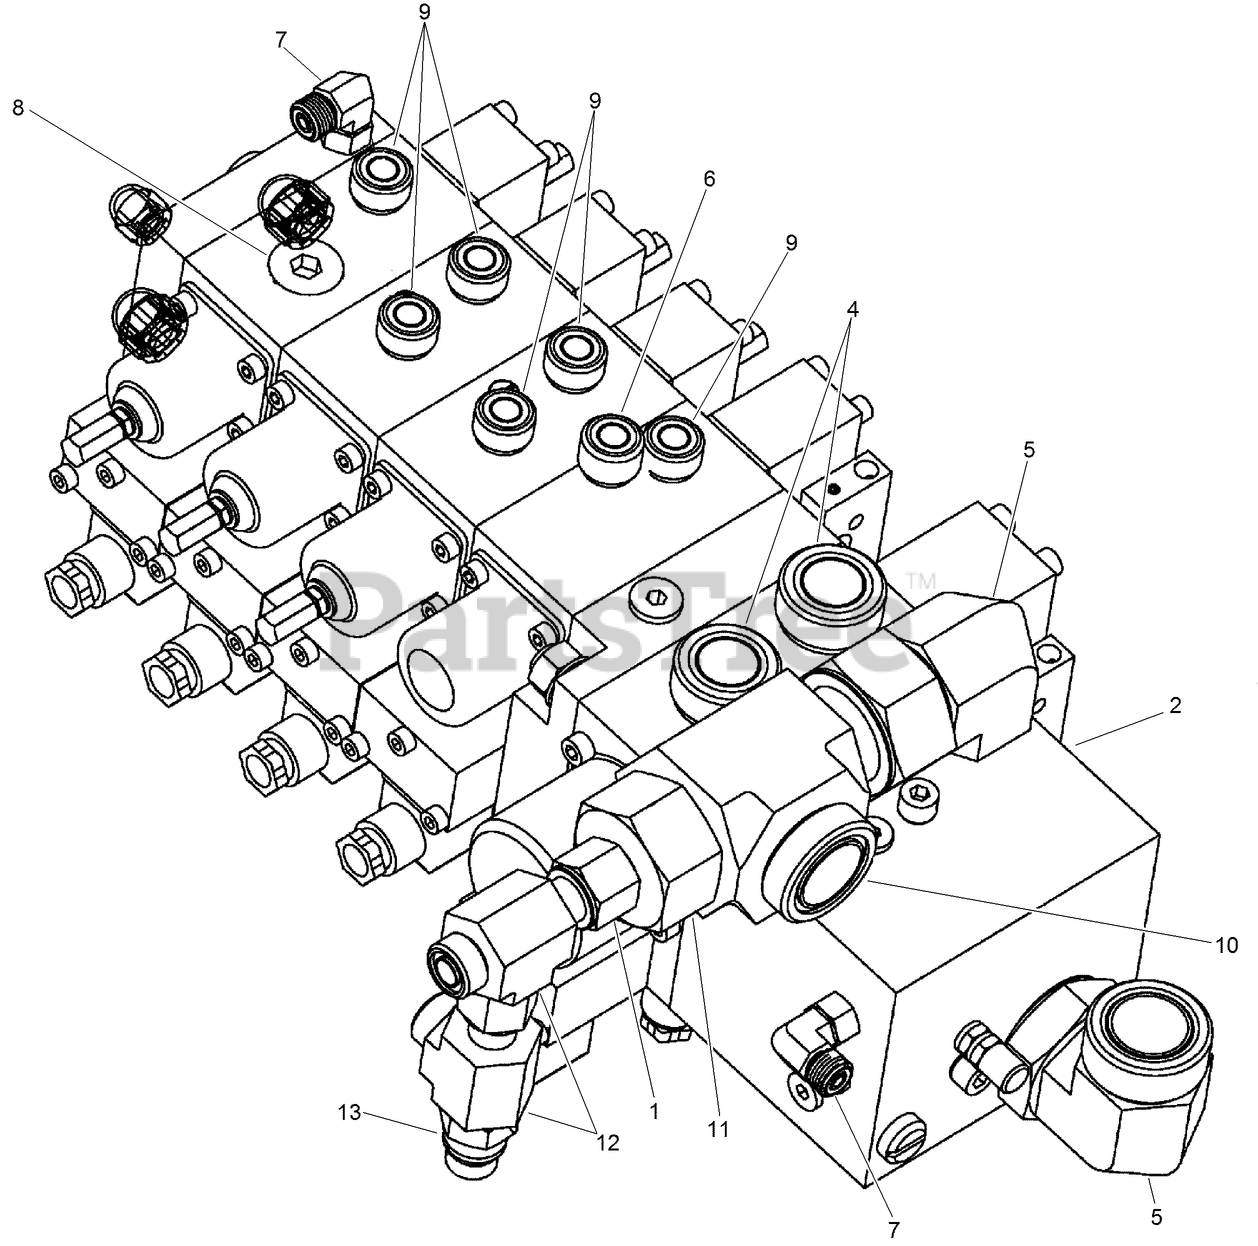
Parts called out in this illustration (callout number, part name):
1	KIT - Hydraulic Fittings
2	5-SECTION HYD VALVE ASM
4	FITTING-STRAIGHT
5	CONNECTION - 90 Deg, -20 ORFS / -20 ORB
6	VALVE-CHECK, 30 PSI
7	CONNECTION - 90 Deg, -4 ORFS / -4 ORB
8	PLUG -10 ORB
9	CONNECTION - Straight, -8 ORFS / -10 ORB
10	FITTING-TEE, RUN
11	FITTING-REDUCER
12	CONNECTION - Run Tee, -8 ORFS / -8 ORFS
13	CONNECTION - Straight, -6 ORFS / -8 ORFS
